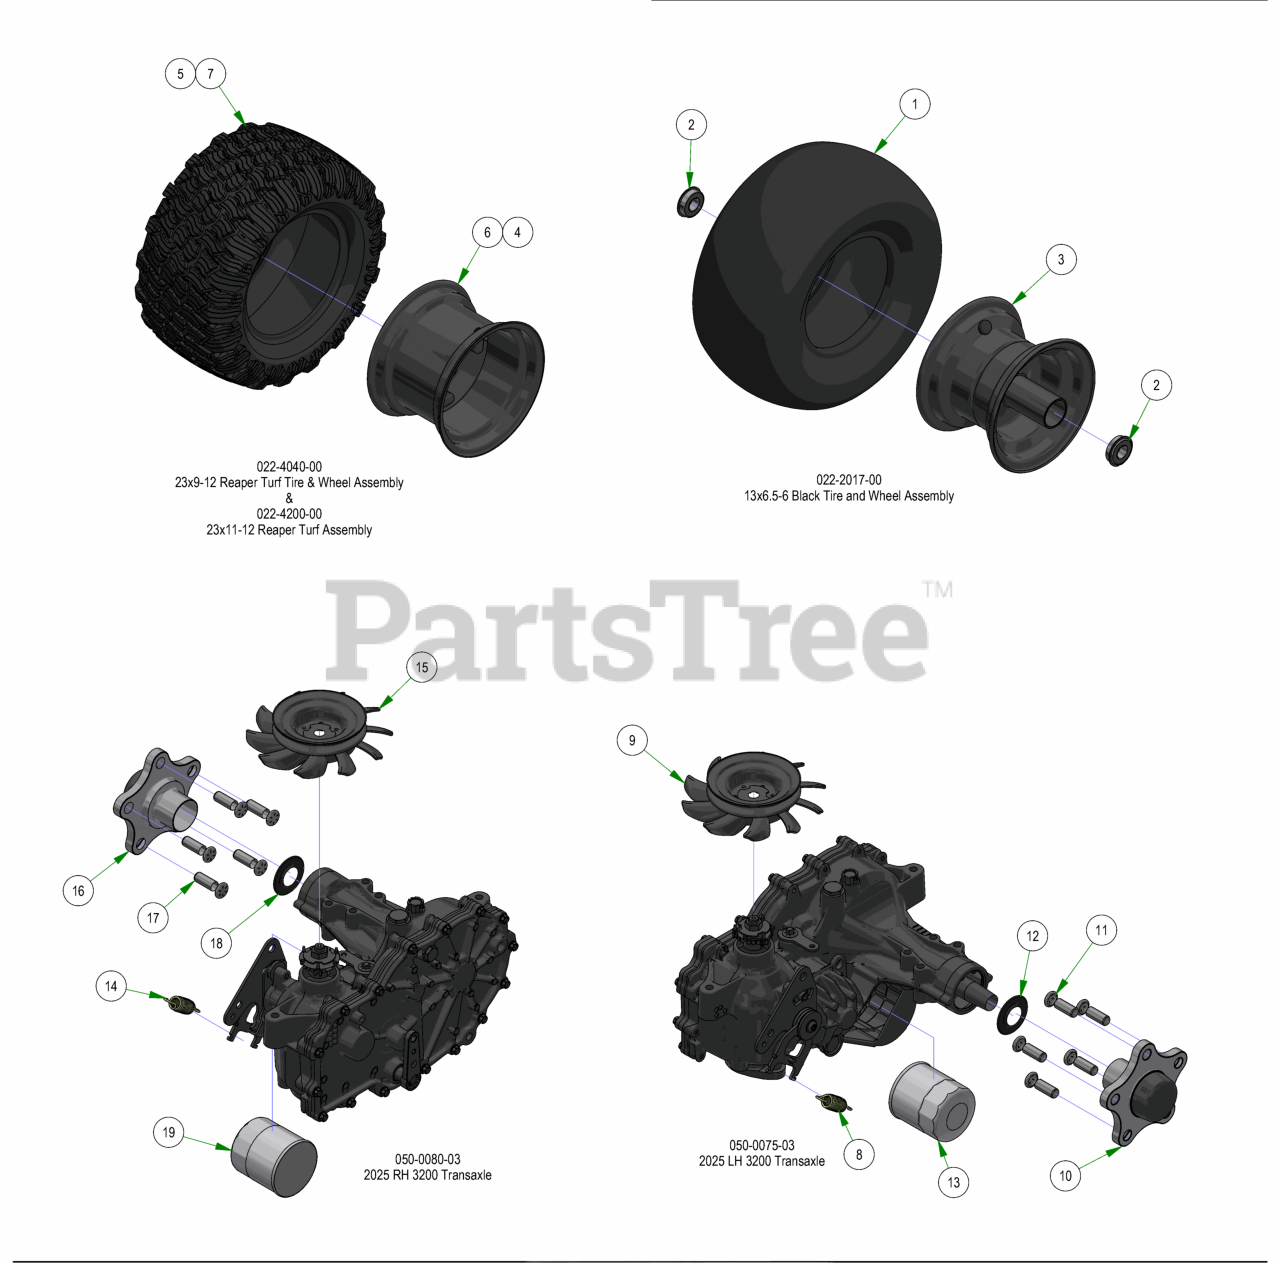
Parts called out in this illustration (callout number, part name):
1	13 x 6.50 - 6 Tire
2	Ball Bearing w/Retainer, 99502H-NR, .625 Bore x 1.375 OD x .4375 Width
3	Front Tire Rim
4	12x7" Black Wheel
5	23x9-12 Reaper Turf Tire Only
6	12x8.5 Black Wheel
7	Tire, 23/11x12 Reaper Turf
8	Transaxle Spring
9	2021 ZT/Maverick Transaxle Fan/Pulley Kit
10	5 Bolt Hub Kit
11	Transaxle Wheel Studs/ Drum Brake Studs
12	2021 ZT/Maverick Transaxle Seat Kit (ZT-2800)
13	ZT Hydraulic Filter
14	Transaxle Spring
15	2021 ZT/Maverick Transaxle Fan/Pulley Kit
16	5 Bolt Hub Kit
17	Transaxle Wheel Studs/ Drum Brake Studs
18	2021 ZT/Maverick Transaxle Seat Kit (ZT-2800)
19	ZT Hydraulic Filter
